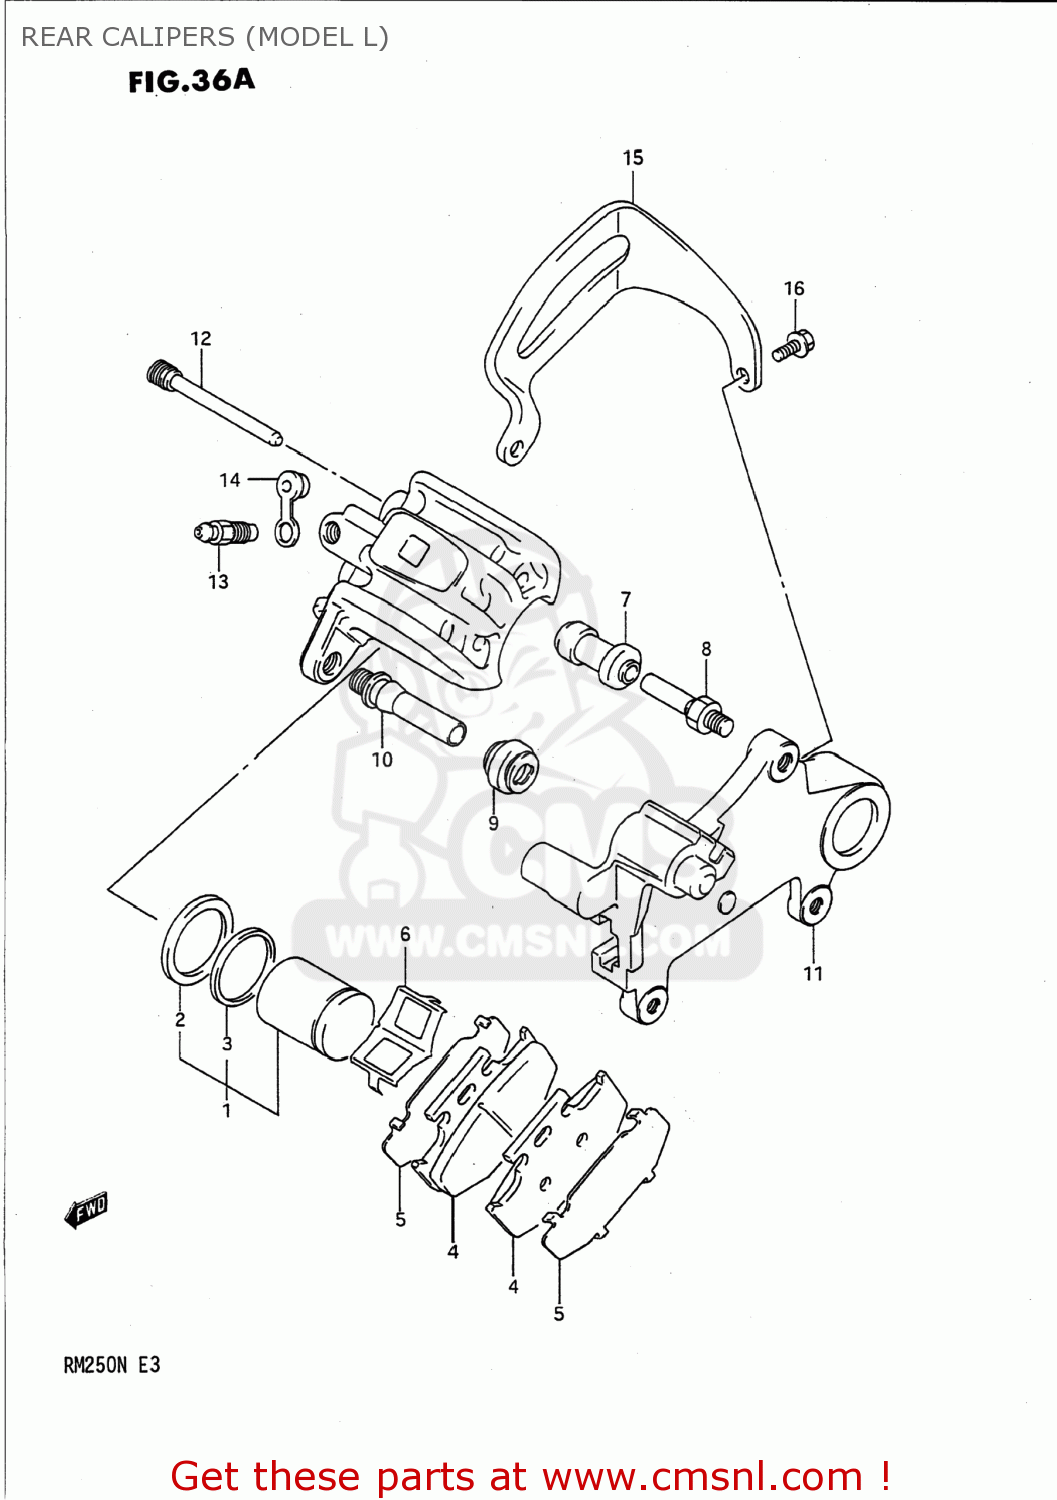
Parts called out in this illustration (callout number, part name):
1	PISTON SET
2	SEAL,PISTON
3	SEAL,DUST
4	PAD
5	SHIM
6	SPRING,PAD
7	BOOT
8	PIN,BOLT
9	BOOT
10	PIN
11	BRACKET
12	PIN,HANGER
13	BLEEDER
14	CAP,BLEEDER
15	GUARD,RR CALIPER
16	BOLT
